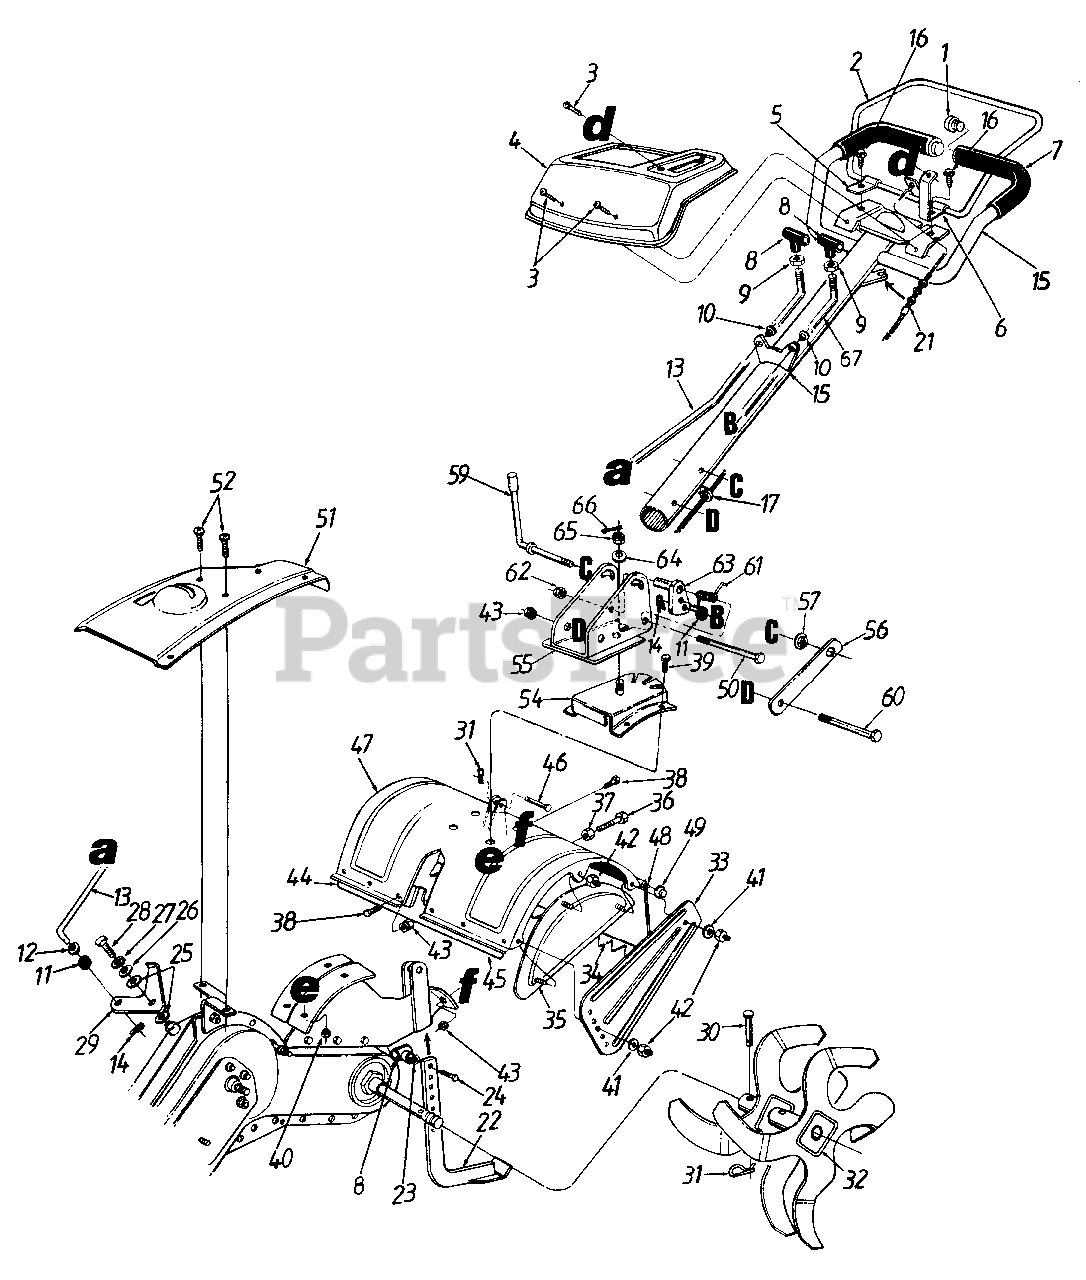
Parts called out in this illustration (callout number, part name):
1	Vinyl End Plug
3	Torx Mach. AB-Tap Scr. 1/4 x .62" Lg.
7	Grip
9	Hex Jam Nut 3/8-16 Thd.
10	Bushing 3/8" I.D.
11	Rubber Washer
12	Fl-Wash. .344" I.D. x .6" O.D.
13	Gear Shift Rod
14	Hairpin Clip
17	Cable Clip
21	Clutch Cable
23	Fl-Wash. 3/8" I.D. x 5/8" O.D.
24	Hex Bolt 3/8-16 x .75" Lg.
25	Washer 1" O.D. (Hdn.)
26	Fl-Wash. .281" I.D. x .73" O.D.
27	L-Wash. 1/4" I.D.
28	Hex Bolt 1/4-20 x .62" Lg. (Gr. 5)
29	Shift Brkt.
30	Clevis Pin
31	Hairpin Clip
36	Hex Cap Bolt 5/16-18 x 1.25" Lg.
37	Hex Nut 5/16-18 Thd.
38	Hex Bolt 5/16-18 x .75" Lg.
39	Carriage Bolt 3/8-16 x 1" Lg.
40	Hex Ins. L-Nut 3/8-16 Thd.
41	Bell-Wash. .345" I.D. x .88" O.D.
42	Hex Cap L-Nut 5/16-18 Thd.
43	Hex Flange Top L-Nut 5/16-18 Thd.
46	Clevis Pin .375" Dia.
49	Cap Speed Nut
50	Hex Bolt 3/8-16 x 3" Lg.
52	Torx Mach. AB-Tap Scr. 1/4 x .6"
57	Hex Flange Nut 3/8-24 Thd.
59	Handle Adjustment Crank
60	Hex Bolt 5/16-18 x 3" Lg.
61	Torsion Spring
62	Hex L-Nut 3/8-16 Thd.
63	Handle Swing Link
64	Bell-Wash. 5/8" I.D.
65	Hex Slotted Nut 5/8-18 Thd.
66	Cotter Pin 1/8" x 1-5/8"
67	Handle Adjustment Rod
